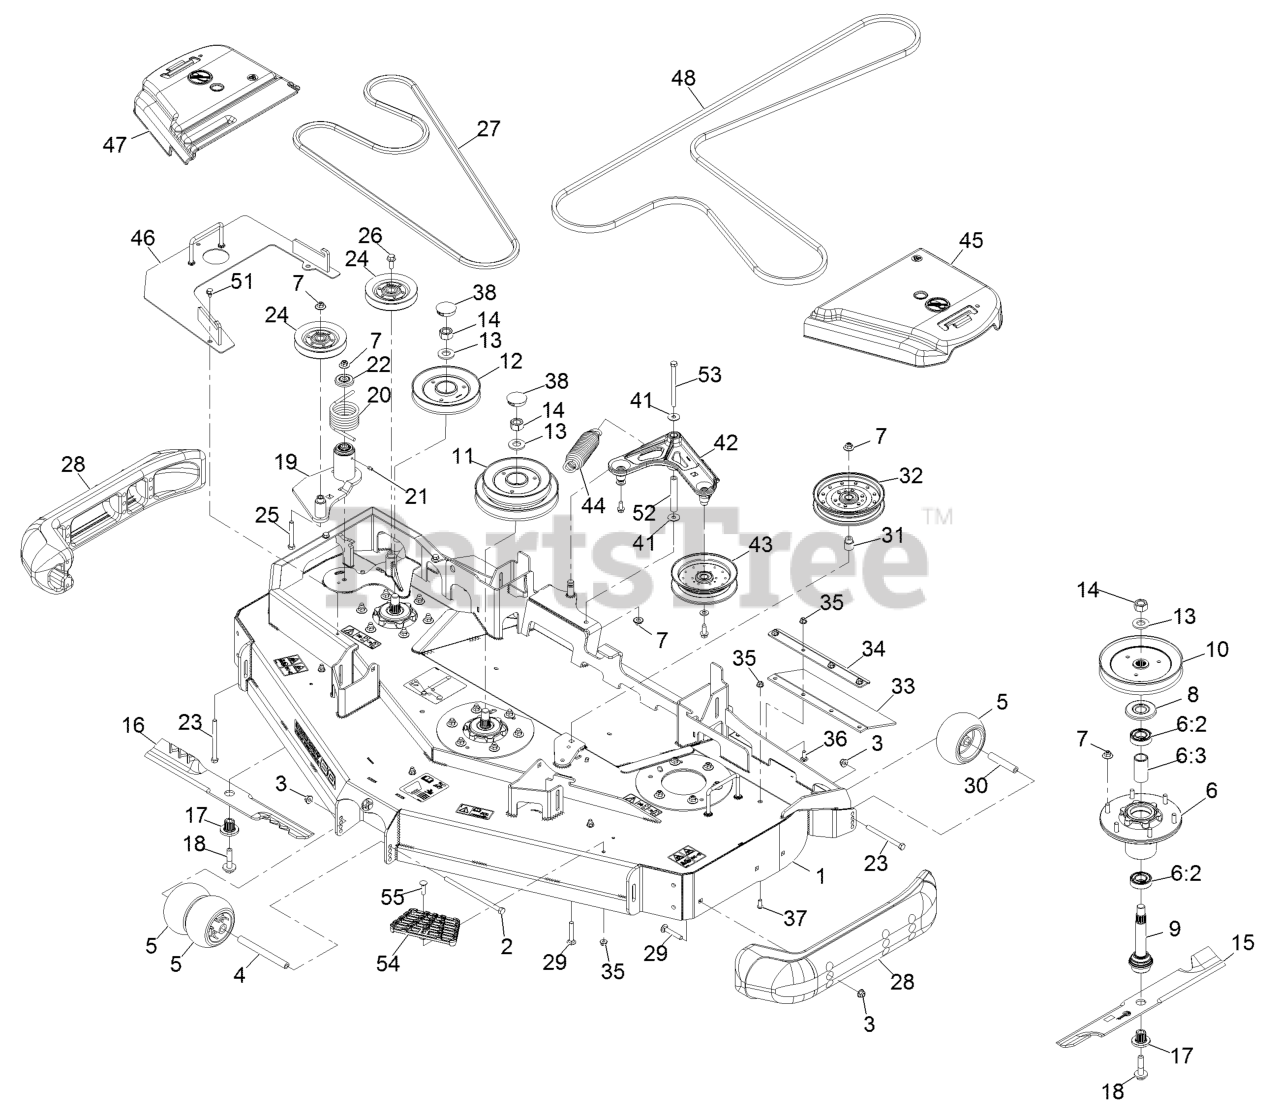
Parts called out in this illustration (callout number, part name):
1	ASM-DECK W/DECALS 60RD
2	SCREW-HH
3	NUT-HF, NI
4	SPACER-WHEEL
5	ROLLER-SCALP, ANTI
6	ASM-CUTTER HSG WITH BEARINGS
6:2	BEARING-BALL
6:3	SPACER-BEARING
7	Nut-Nyloc 3/8-16 Flg
8	GUARD,BEARING TOP .989
9	ASM-SPINDLE AND SEAL
10	SHEAVE,BLADE DRIVE 7.25
11	SHEAVE, DOUBLE 60RD
12	SHEAVE-RD REV DRIVE SERIE
14	NUT-HEX
15	Blade-Extreme 2, 20.50"
16	Blade-Extreme 2-20.50, Rd60
16	Blade-Low Lift 20.5, Rd60
17	BUSHING,SPLINED
18	SCREW,SEMS 1/2-20 X 2.19
19	IDLER ASM
20	SPRING-TORSION
21	FITTING-GREASE
22	GUARD-TOP
23	SCREW-HH
25	SCREW-HH
26	SCREW-HHF
27	BELT
28	SKID-BUMPER, DECK
29	Bolt-Carriage 3/8-16 X 2 1/4
30	TUBE-SPANNER
31	BUSHING-IDLER
32	IDLER-PULLEY, FLAT 6.00X1
33	GUARD-TIRE
34	SUPPORT-OUTER FLAP
35	NUT-HF, NI
36	SCREW-CARR
37	SCREW-HSBH
38	PLUG,BLACK NYLON 1.75
42	IDLER ARM ASM
43	IDLER-PULLEY, FLAT
44	SPRING-EXTENSION
45	COVER-BELT, LH
46	COVER-DRIVE, REVERSE
47	COVER-BELT, RH
48	BELT-V
52	BUSHING
53	SCREW-HH
54	STEP-DECK
55	Bolt-Carriage 5/16-18 X 1 1/4
